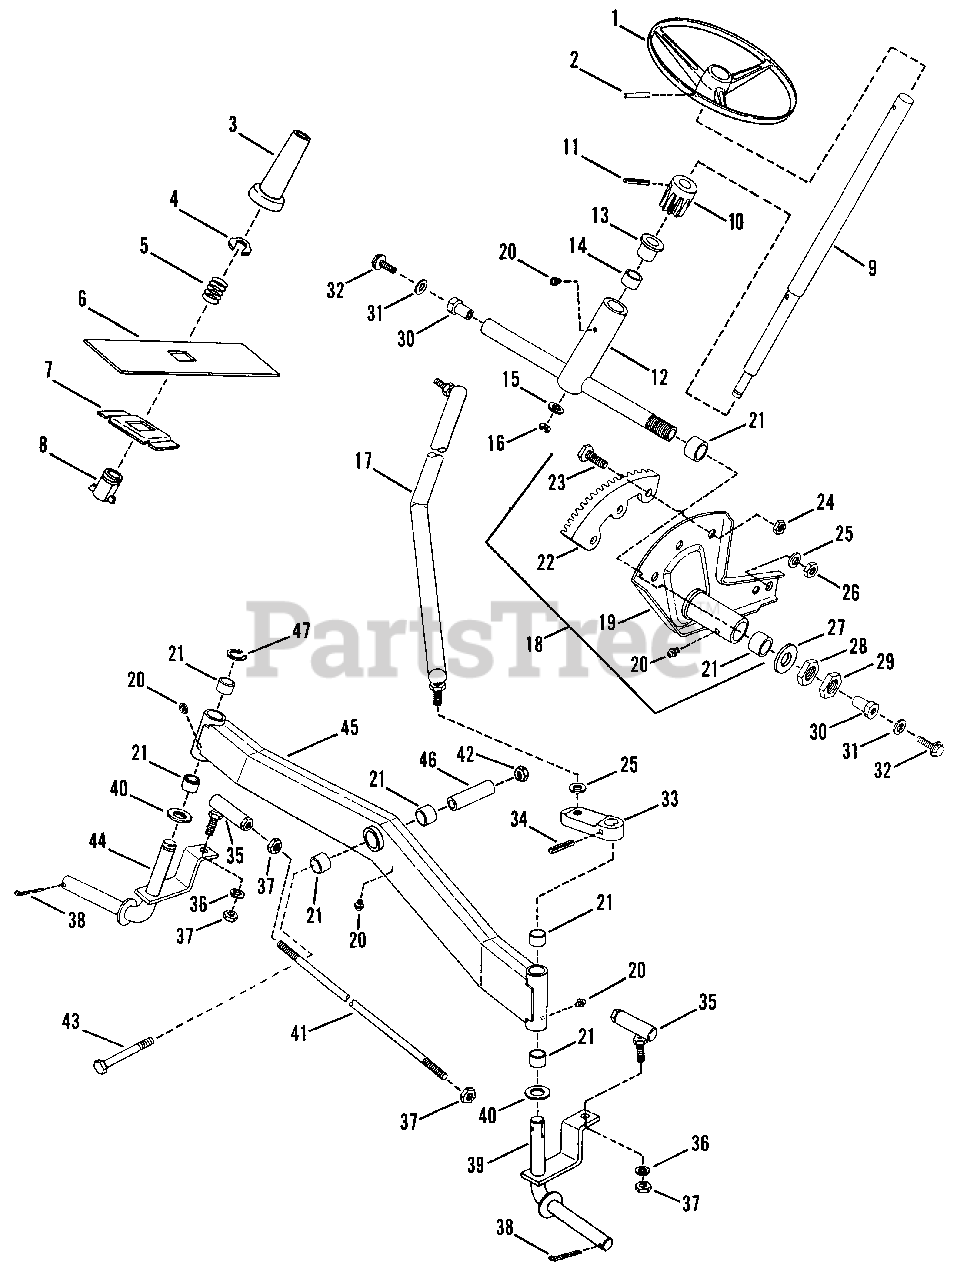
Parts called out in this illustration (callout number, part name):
1	STEERING WHEEL
2	ROLL-PIN
3	ACTUATOR, Steering Lock
4	RING, Retaining
5	SPRING, Actuator
6	COVER, Slide
7	RISER, Steering Lock
8	BUSHING, Steering Lock
9	SHAFT, Steering
10	PINION, Steering
11	ROLL-PIN
12	ASSEMBLY, Bearing Support
13	BEARING, Flange
14	BUSHING
15	WASHER, 3/8" Flat
16	RING, Retaining
17	DRAG-LINK
18	ASSEMBLY, Steering Sector
19	ASSEMBLY, Sector
20	LUBE FITTING, Straight (press-fit for .187 dia. Hole)
21	BEARING
22	GEAR, Steering Sector
23	SCREW, 1/4-20 x 5/8" Hex Head Cap
24	NUT, 1/4-20 Hex Center Lock
25	WASHER, 1/2 Split Lock
26	NUT, 1/2-20 Hex
27	WASHER, 3/4 SAE Flat
28	NUT, 3/4-16 Hex
29	NUT, 3/4-16 Hex Jam
30	PIVOT
31	WASHER, 5/16 Internal Tooth Lock
32	SCREW, 5/16C x 3/4" Self-Tapping
33	ARM, Steering
34	ROLL-PIN
35	BALL JOINT, 3/8-24 Thread
36	WASHER 3/8 Split Lock
37	NUT, 3/8-24 Hex
38	COTTER-PIN
39	KING-PIN, Left Side
40	WASHER, Thrust
41	TIE-ROD
42	NUT, 1/2-20 Hex Lock
43	SCREW, 1/2-20 x 4" Hex Head Cap
44	KING-PIN, Right Side
45	ASSEMBLY, Front Axle
46	JOURNAL, Axle
47	RING, Retaining
